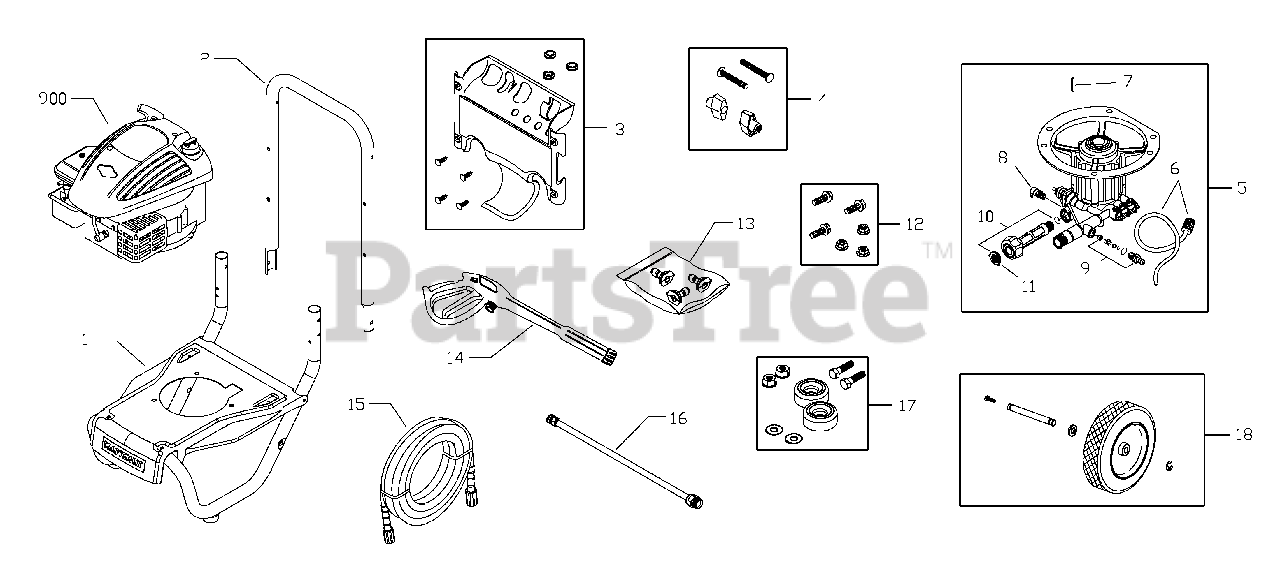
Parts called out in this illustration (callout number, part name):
2	Handle
3	Kit, Billboard w/Decals
4	Kit, Handle Connector
6	Kit, Chemical Hose
8	Valve, Thermal Relief
9	Kit, Chemical Injection
10	Kit, Water Inlet
12	Kit, Pump Mounting Hardware
14	Gun
15	Hose
16	Extension, QC
17	Kit, Vibration Mount
18	Kit, Wheel
900	Engine
